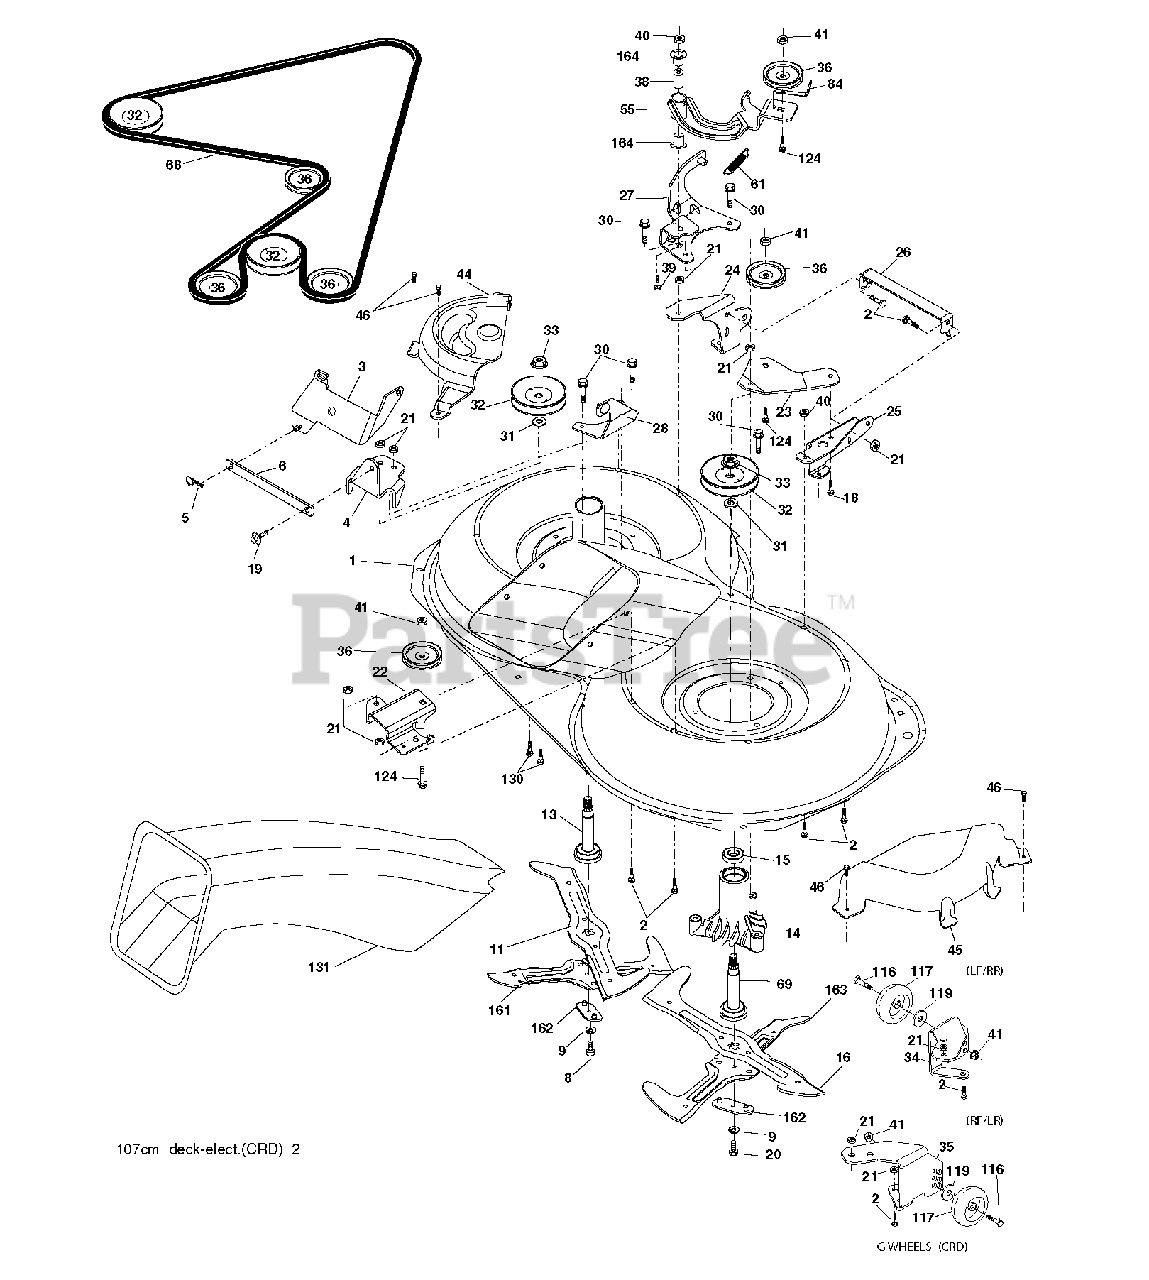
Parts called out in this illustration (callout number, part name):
2	BOLT
3	BRACKET
5	RETAINER-SPRNG RB
6	BAR SWAY
9	LOCKWASHER
11	BLADE.3N1.LH.CRD
13	SHAFT ASM VENT
14	HSG MANDREL
16	BLADE.3N1.RH.CRD
19	BOLT SHD 5/16-18
21	LOCKNUT
22	BRACKET
23	BRACKET
27	BRACKET
30	SCREW, WASHER HEAD
31	WASHER.SPACER.MANDREL
33	NUT.FLANGE.LOCK.TOP
36	PULLEY.IDLER.4.25
40	LOCKNUT
41	NUT LOCK FLG 3/8-16 UNC
45	MANDREL COVER
46	SCREW.1/4-20X5/8
55	ARM IDLER
68	HEX-BELT 107 MOWER
69	SHAFT.ASM.W/LWR.BRG.RH.THREAD
84	KEEPER, BELT IDLER
116	BOLT.SHOULDER.3/8-16X3-5/8
117	WHEEL. GUAGE RALLY
124	BOLT.3/8-16X1.50
131	CHUTE BAGGER
164	BRNG T
